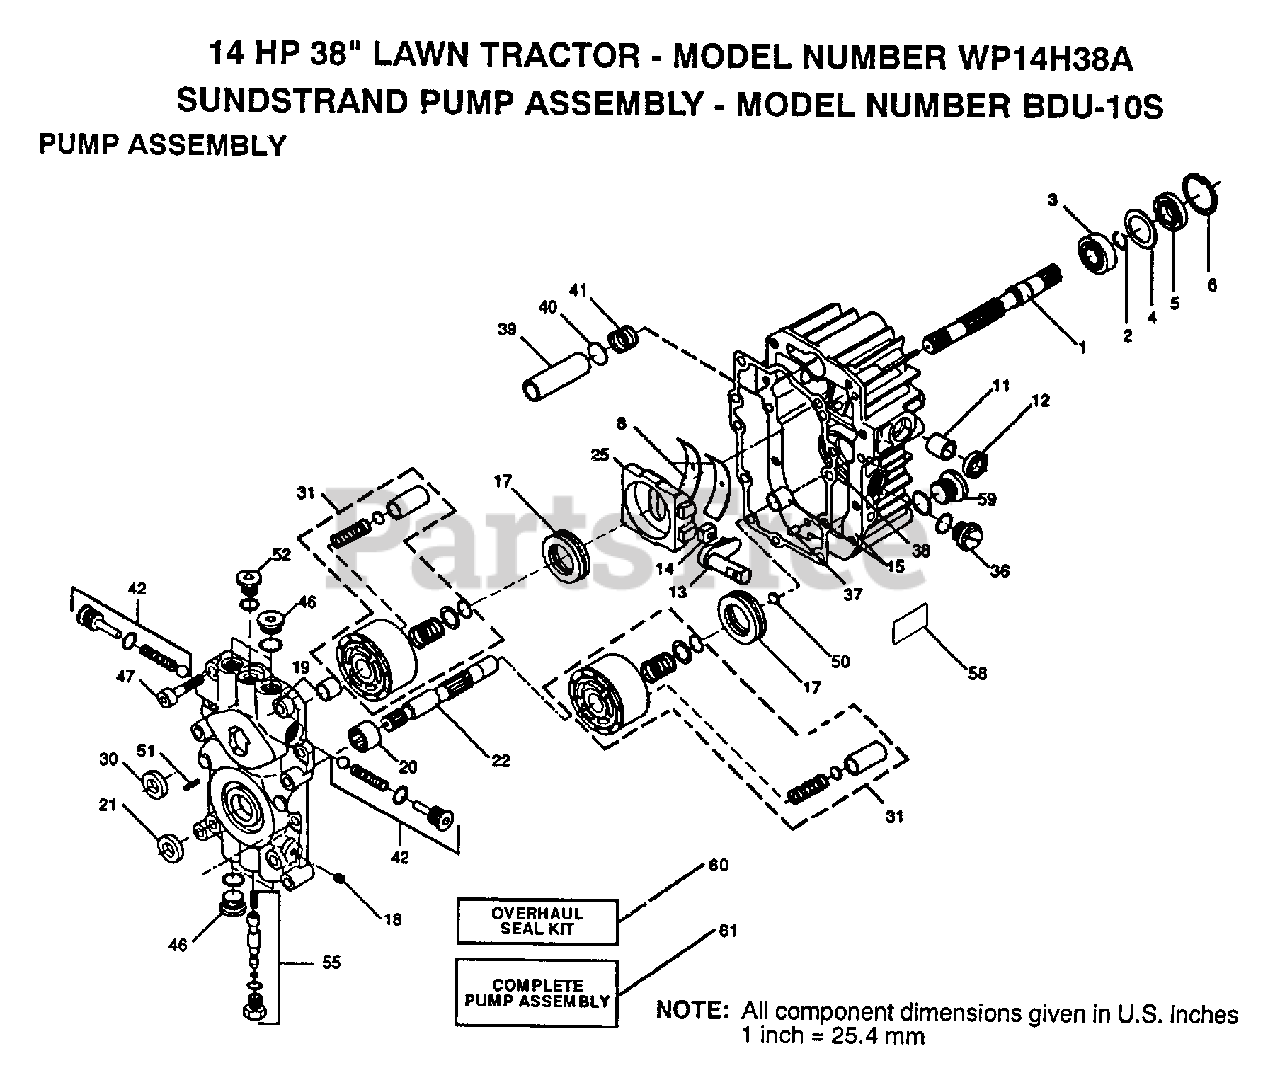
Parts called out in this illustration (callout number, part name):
1	SHAFT.PU.2003022
2	RING, RETAINING
3	BALL BEARING
4	SPACER
5	SEAL LIP
6	RING.RET.2003052
8	CRADLE BEARING (2003023)
11	BEARING
12	SEAL.9008000-0126
13	TRUNION ARM (2003005)
14	GUIDE.2000015.HYD
18	PLUG PIPE
19	"KIT,CTR SECTION (2513007)"
20	NEEDLE BEARING
21	LIP SEAL-9008000-0127
22	SHAFT
25	"SWASHPLATE,VARIAB"
30	SEAL LIP
31	"KIT,BLOCK CYLINDE"
36	"PLUG,PLASTIC 9005200-8700"
37	PIN
38	GASKET.20030600
39	FILTER
40	WASHER (2000011)
41	SPRING
42	KIT.VALVE.2513014
46	PLUG
47	SCREW9007314-0808
50	WASHER
51	PIN
52	PLUG
55	"KIT,BYPASS VALVE"
58	PLUG
59	"KIT,OVERHEAD SEAL -2513013"
60	PUMP.BDU-10S-114
